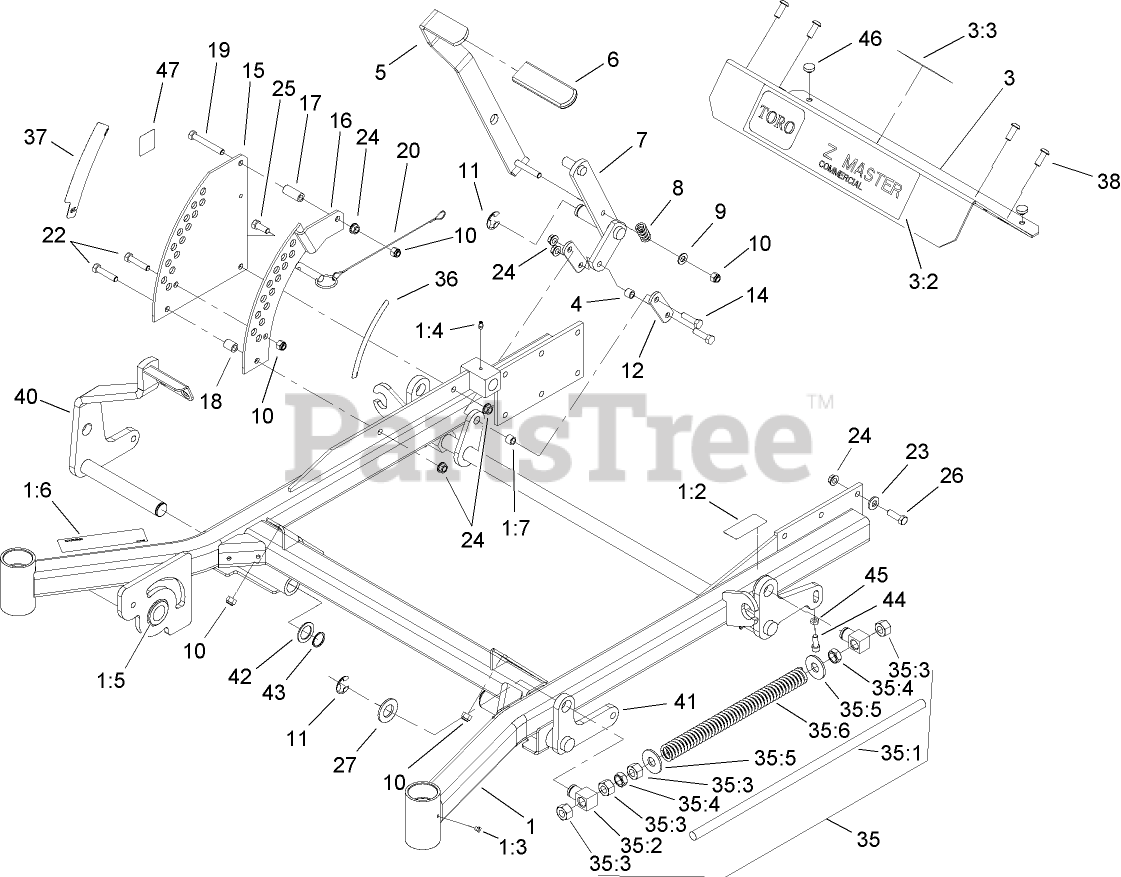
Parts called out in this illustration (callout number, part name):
1	FRAME ASM
1:2	DECAL-BRAKE, PARKING
1:4	FITTING-GREASE
1:5	BUSHING
1:6	DECAL-WARNING
1:7	Bushing
3	FOOTREST
3:3	DECAL-DANGER, SLOPE
4	Bushing
5	LEVER-LIFT
6	GRIP-LEVER, LIFT
7	ARM-LIFT, DECK
8	SPRING-COMPRESSION
9	WASHER-FLAT
10	NUT-LOCK, NI
11	RING-RETAINING, EXT
12	ARM-LIFT, DECK
14	SCREW-HH
15	PLATE-LIFT, DECK
16	PLATE-LIFT, DECK
17	BUSHING-LEVER, LIFT
18	BUSHING-LEVER, LIFT
19	SCREW-HH
20	Hitch Pin ASM
22	SCREW-HH
23	WASHER-BELLEVILLE
24	NUT-HHF, WHIZ
25	SCREW-HH
26	SCREW-HH
27	WASHER-FLAT
35	Front Frame Spring ASM
35:1	ROD-LIFT, DECK
35:2	SWIVEL-DECK MOUNT, REAR
35:3	NUT-HEX
35:4	NUT-JAM
35:5	WASHER-FLAT
35:6	SPRING-SUPPORT, DECK
36	DECAL-HEIGHT, DECK
37	DECAL-HEIGHT, DECK
38	SCREW-HSBH
40	RH Deck Lift ASM
41	LIFT-DECK, LH
42	WASHER-SPACER
43	RING-RETAINING
44	SCREW-HSH
45	NUT-JAM
46	BUMPER
47	DECAL-NOISE
